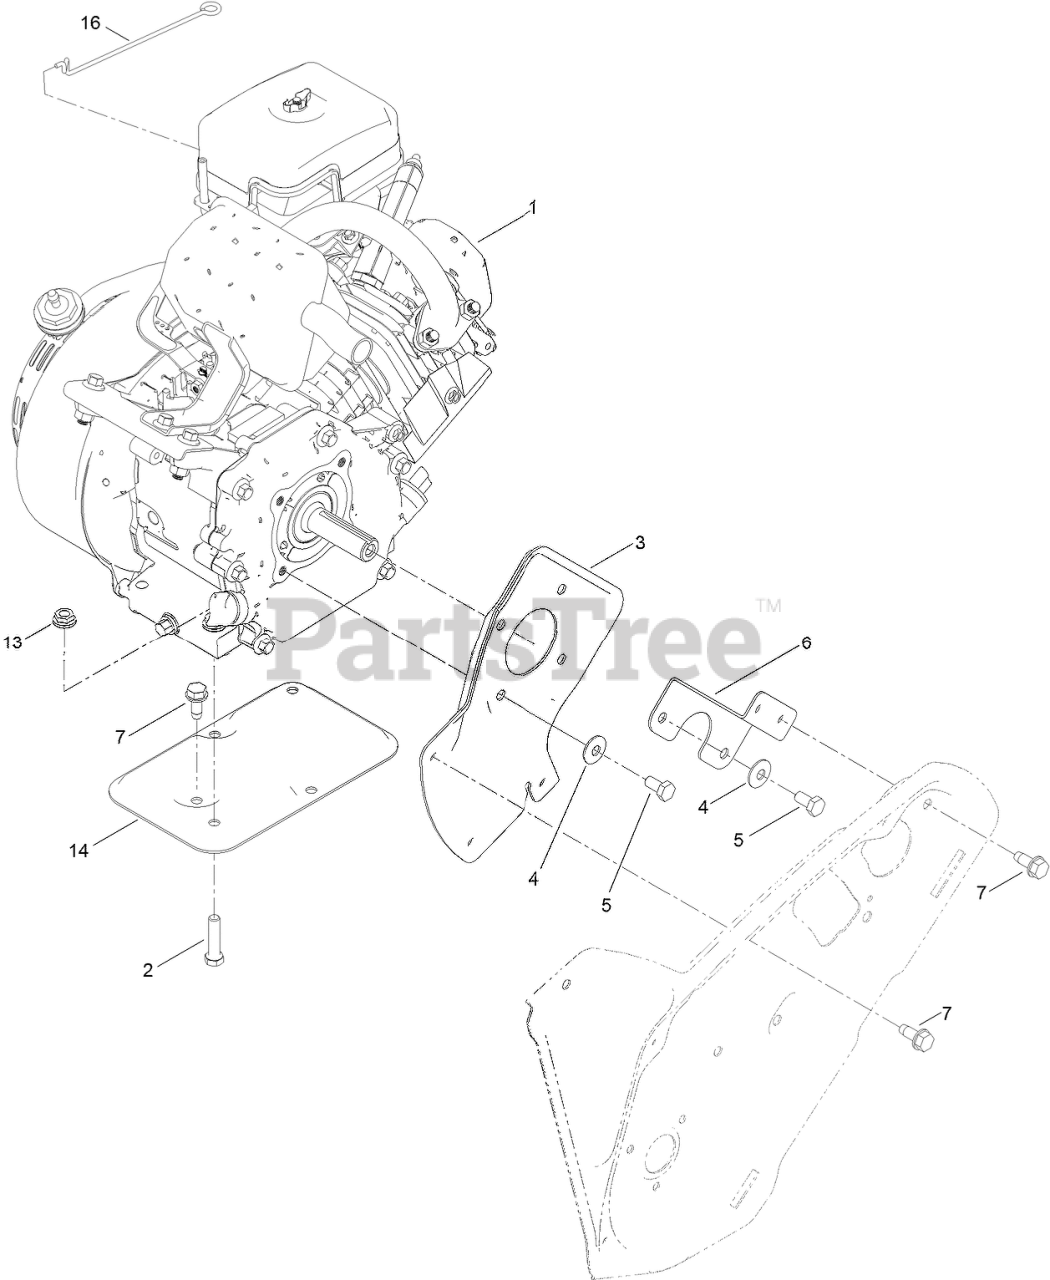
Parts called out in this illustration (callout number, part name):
1	ENGINE-170FS-2
2	SCREW-HH
3	PLATE-ENGINE, PTO
4	WASHER-BELLEVILLE
5	SCREW-HH
6	SUPPORT-ENGINE, SIDE
7	SCREW-THD ROLL, HWH
13	NUT-HF
14	SUPPORT-ENGINE
16	LINK-CHOKE
